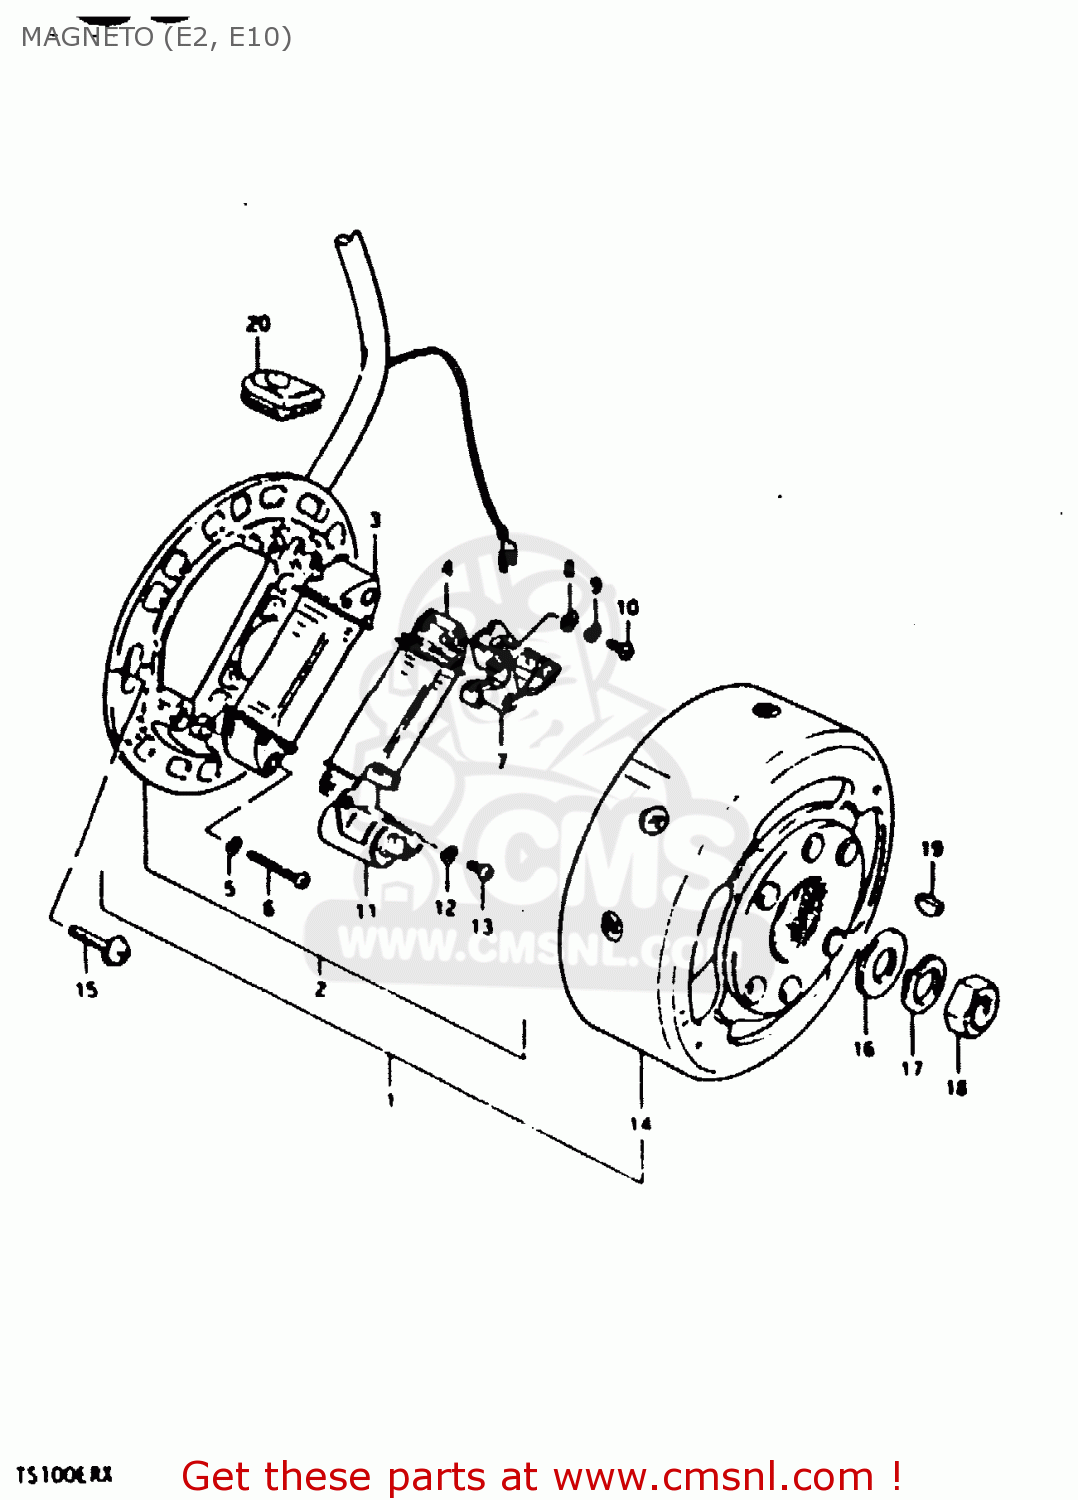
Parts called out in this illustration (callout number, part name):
1	MAGNETO ASSY
2	STATOR ASSY
3	COIL, LIGHTING
4	COIL,PRIMARY
5	LOCK WASHER
6	SCREW (4X30)
7	POINT ASSY,CONTACT
8	WASHER
9	LOCK WASHER
10	SCREW(4X10)
11	CONDENSER
12	LOCK WASHER
13	SCREW
14	ROTOR, FLYWHEEL
15	SCREW(5X14)
16	WASHER
17	LOCK WASHER
18	NUT (10MM)
19	KEY
20	GROMMET
